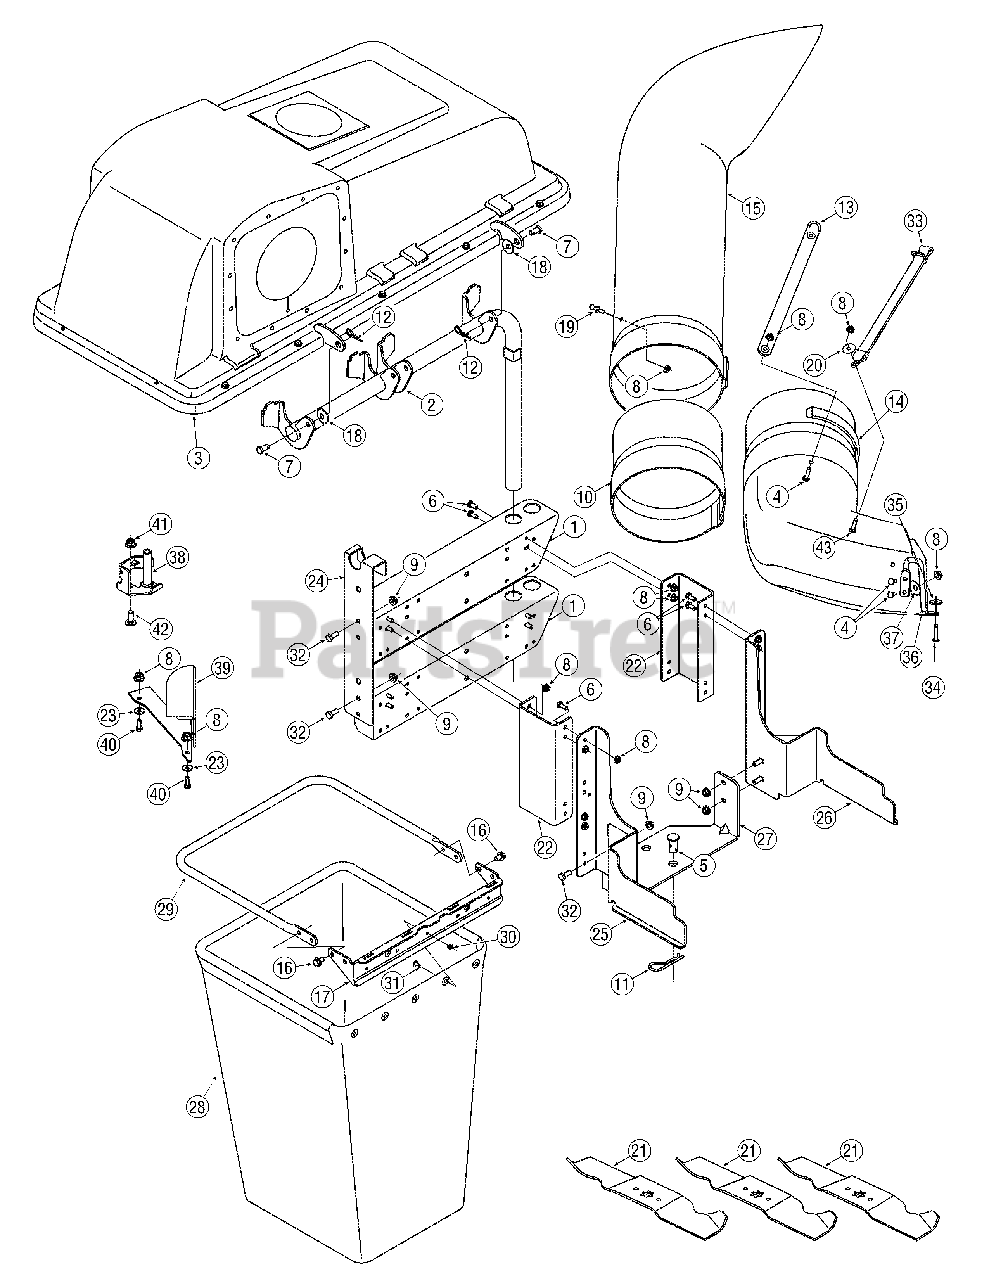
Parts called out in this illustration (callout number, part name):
3	Grass catcher Cover Assembly
4	Screw 1/4-20 x 1"
5	Clevis Pin
6	Hex Screw 1/4-20 x0.620
7	Clevis Pin
8	Flange Lock Nut, 1/4-20
9	Flange Lock Nut, 5/16-18
10	Extension Tube
11	Hairpin Clip
12	Click Pin
13	Chute Strap - 50" Deck
14	Discharge Chute - 50" Deck
15	Catcher Tube
16	Self-Tapping Screw 5/16-18
18	Bell Washer
19	Grass catcher Pin
20	Flat Washer
28	Catcher Bag
30	Hex Sems Nut, #10-24
31	Machine Screw, , #10-24 x .5
32	Hex Screw 5/16-18 x 0.75"
33	Chute Strap
34	Pop Rivet
35	Washer, Flat, .194 x .62 x .063
36	Bag Mount Rod
37	Washer, Flat, .28 x .74 x .063
40	Hhcs, 1-4/20 x .75
41	Nut, Lock, Flange, 3/8-16
42	Bolt, Carriage, 3/8-16 x 1.00
43	Screw 1/4-20 x 1.25"
